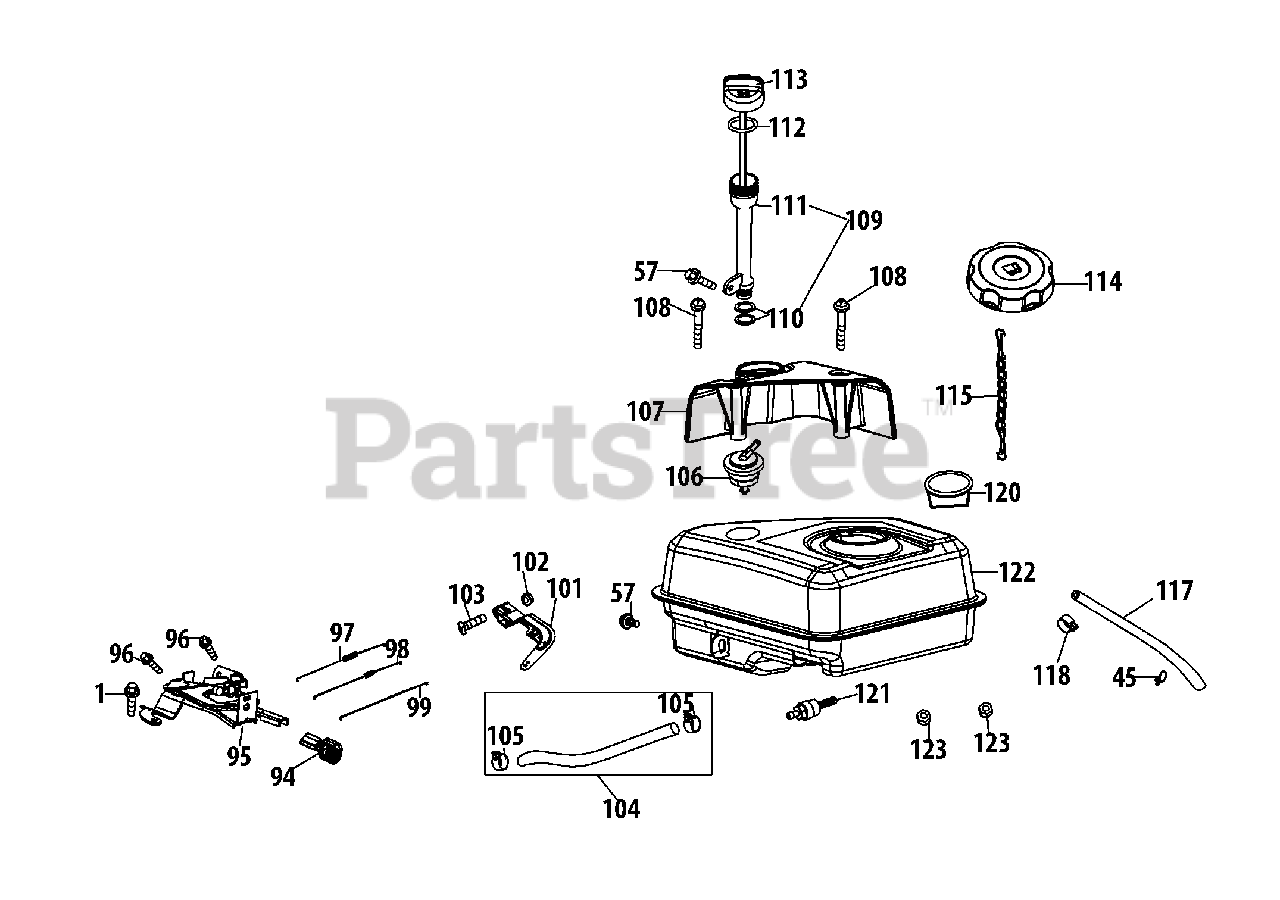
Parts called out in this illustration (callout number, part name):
1	Bolt M6×16
57	Bolt M6×12
94	Throttle Control Knob
95	Primer Bracket
96	Bolt M6×12
97	Governor Spring
98	Throttle Linkage Spring
99	Governor Rod
101	Governor Arm Bracket
102	Nut M6
103	Governor Arm Bolt
104	Fuel Line Kit
105	Fuel Hose Clamp
106	Valve, Roller Over
107	Engine Dipstick Cover
109	Oil Fill Tube Assembly
110	Dipstick O-Ring
111	Dipstick Tube
112	O-Ring
113	Dipstick Assembly
114	Fuel Cap
115	Fuel Cap Chain
117	Primer Hose Assembly
120	Fuel Level Indicator
121	Fuel Tank Nipple
122	Fuel Tank
123	Nut M6
